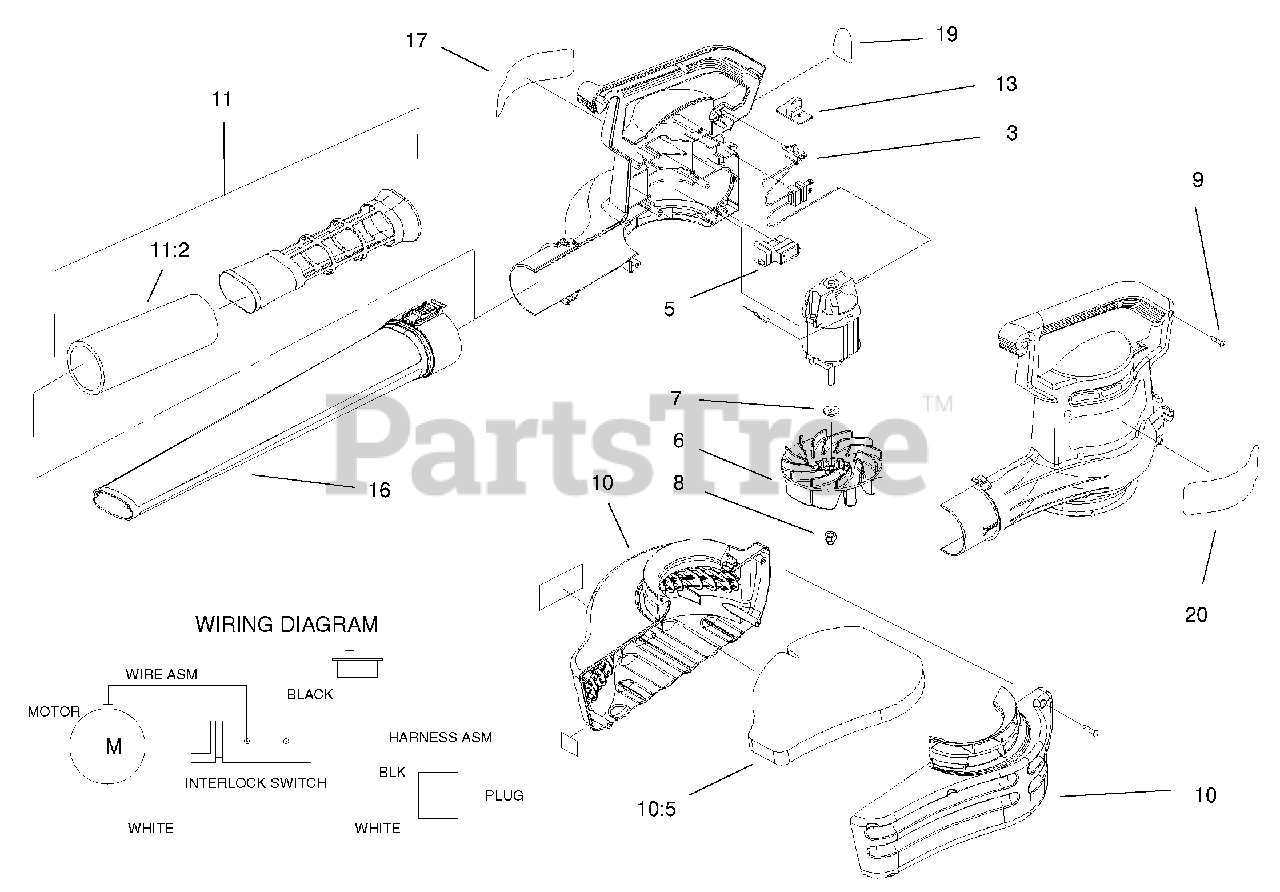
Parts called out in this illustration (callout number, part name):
3	Wire Harness
5	Switch-Interlock
6	Impeller-Blower
8	Nut-Hex
9	Screw-PPH
10	ASM-Quietech Inlet Cover
10:5	Foam-Inlet
11	ASM-Quietech Tube Insert
11:2	Foam-Insert
16	Tube-Blower
17	Decal-Warning
19	Decal-Information
20	Decal-Logo, Suprblower
